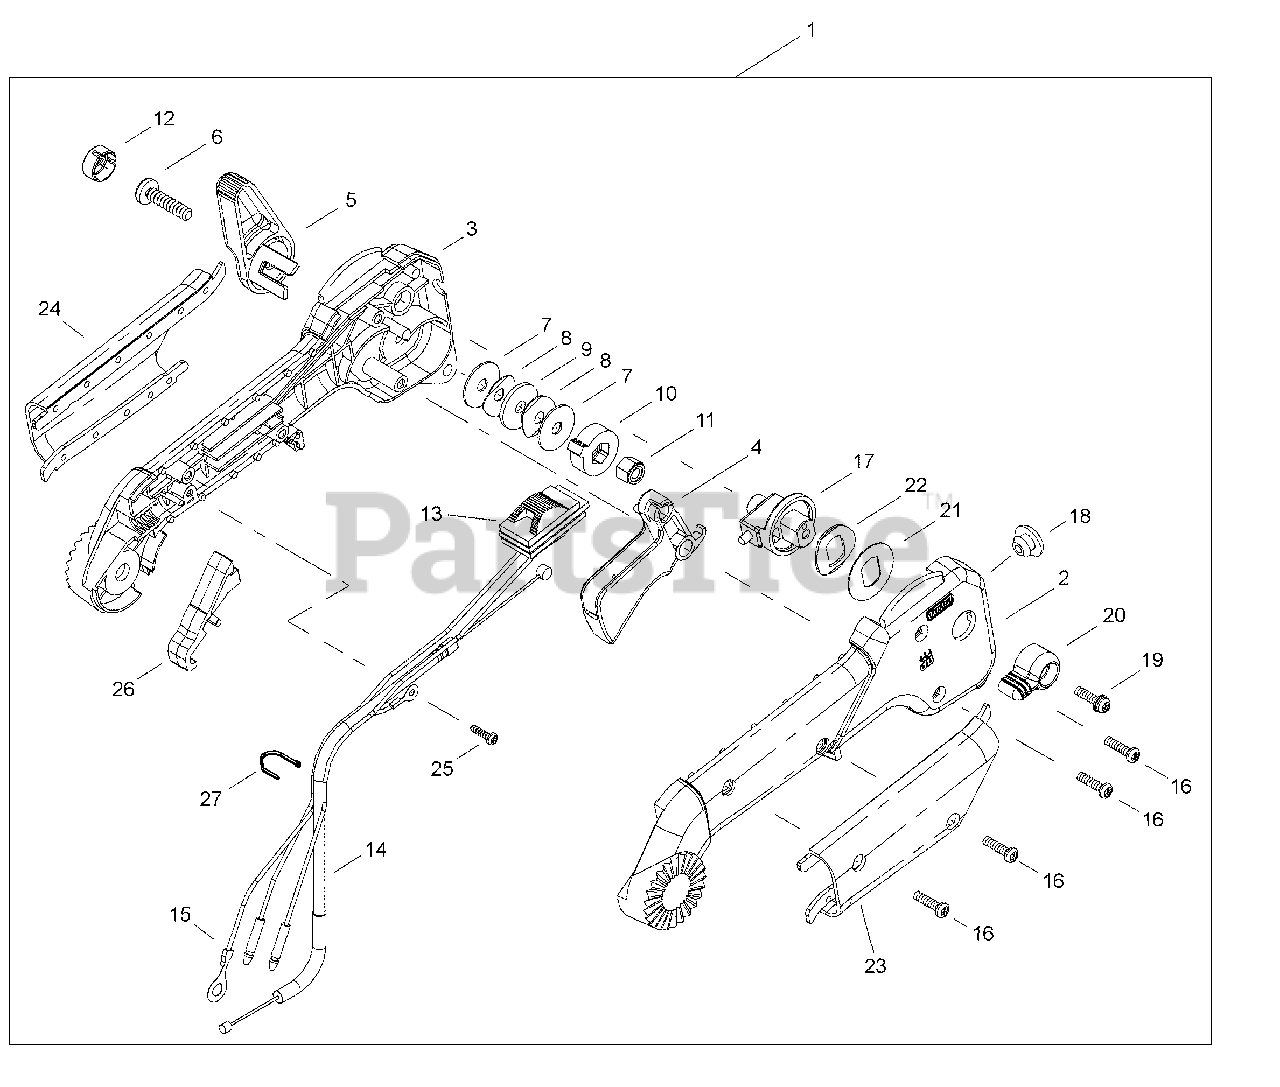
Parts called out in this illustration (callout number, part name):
1	THROTTLE CONTROL ASSY
2	CONTROL HANDLE - RIGHT
3	CONTROL HANDLE - LEFT
4	TRIGGER, THROTTLE
5	CONTROL, THROTTLE
6	BOLT M6×25
7	WASHER M6
8	WASHER, SPRING
9	WASHER M6
10	LEVER, THROTTLE
11	NUT, NYLON M6
12	CAP, BOLT
13	SWITCH, IGNITION
14	CABLE, THROTTLE
15	LEAD - GROUND
16	SCREW M4×16
17	LIMITER ASSY, THROTTLE
18	PLUG, THROTTLE LIMITER
19	SCREW M4×16
20	LEVER, THROTTLE LIMITER
21	WASHER
22	WASHER, WAVE
23	GRIP, RIGHT
24	GRIP, LEFT
25	SCREW M3×8
26	COVER, HANDLE REAR
27	BAND
